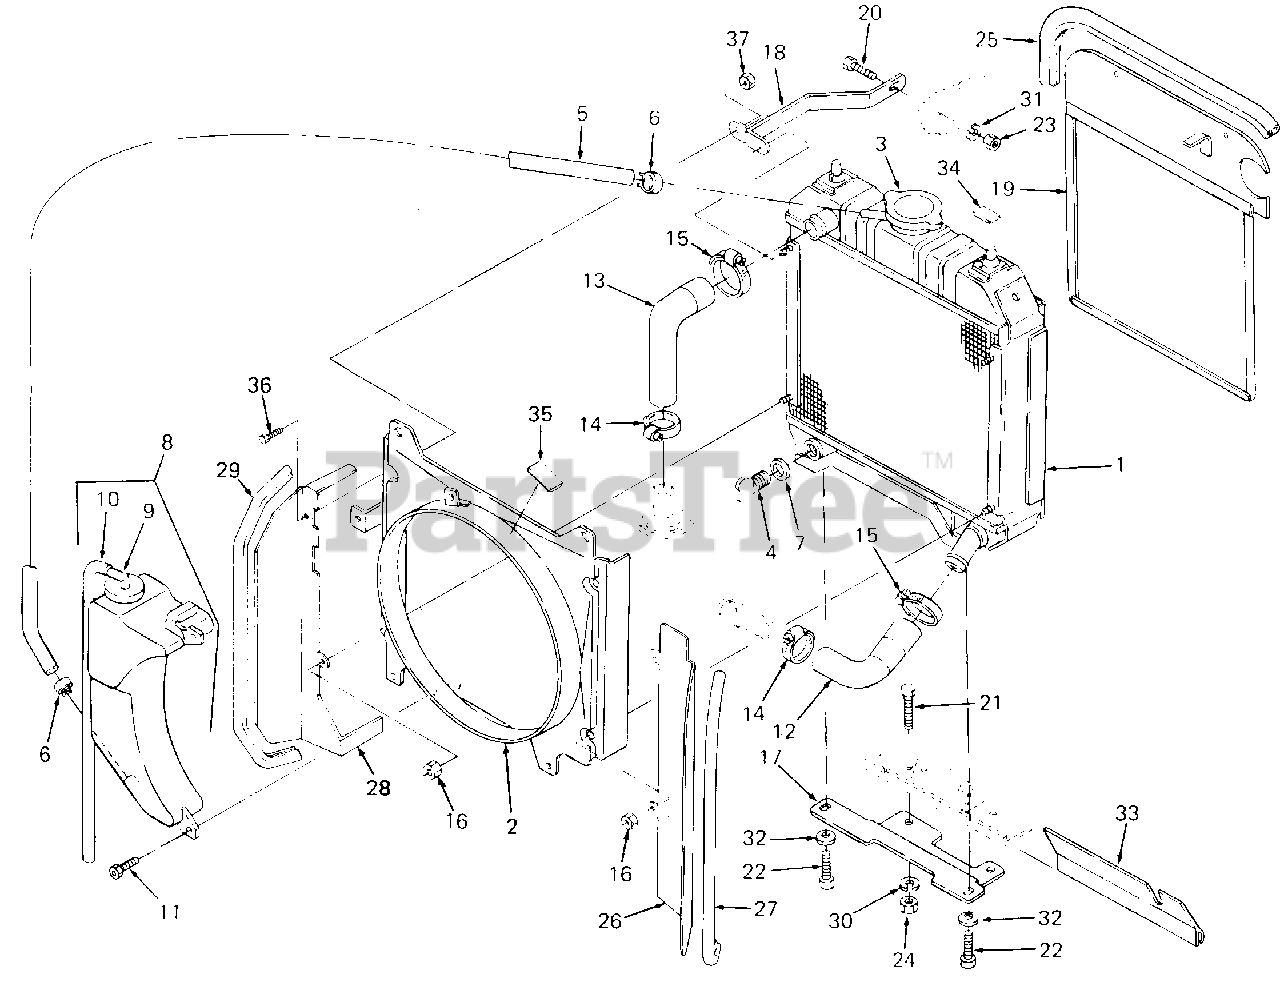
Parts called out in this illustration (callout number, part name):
1	Radiator Assy
5	Pipe, Water Overflow
8	Tank Assy, Reserve
10	Pipe, Overflow
17	Mount, Radiator
18	Brace, Radiator
19	Heat Baffle Assy
20	Screw, Hex Cap, 1/4-20 X .62 Lg GR5
21	Screw, Hex Cap, 5/16-18 X .75 Lg GR5
22	Screw, Hex Cap, M10 X 1.25 X 25 mm Lg GR8
23	Nut, Hex, 1/4-20 GR5
24	Nut, Hex, 5/16-18 GR5
25	Seal, Baffle, 17" Lg
26	Baffle, Radiator LH
27	Seal, Baffle, 15" Lg
28	Baffle, Radiator RH
29	Seal, Baffle, 16" Lg
30	Washer, Lock, 5/16 Dia
31	Washer, Lock, 1/4 Dia
32	Washer, Bell, .45 X 1.0 X .062
33	Flap, Radiator Bottom
34	Label, Radiator
35	Label, Radiator
36	Screw, Hex Cap, 1/4-20 X .375 Lg
37	Nut, Hex Center Lock, 1/4-20
